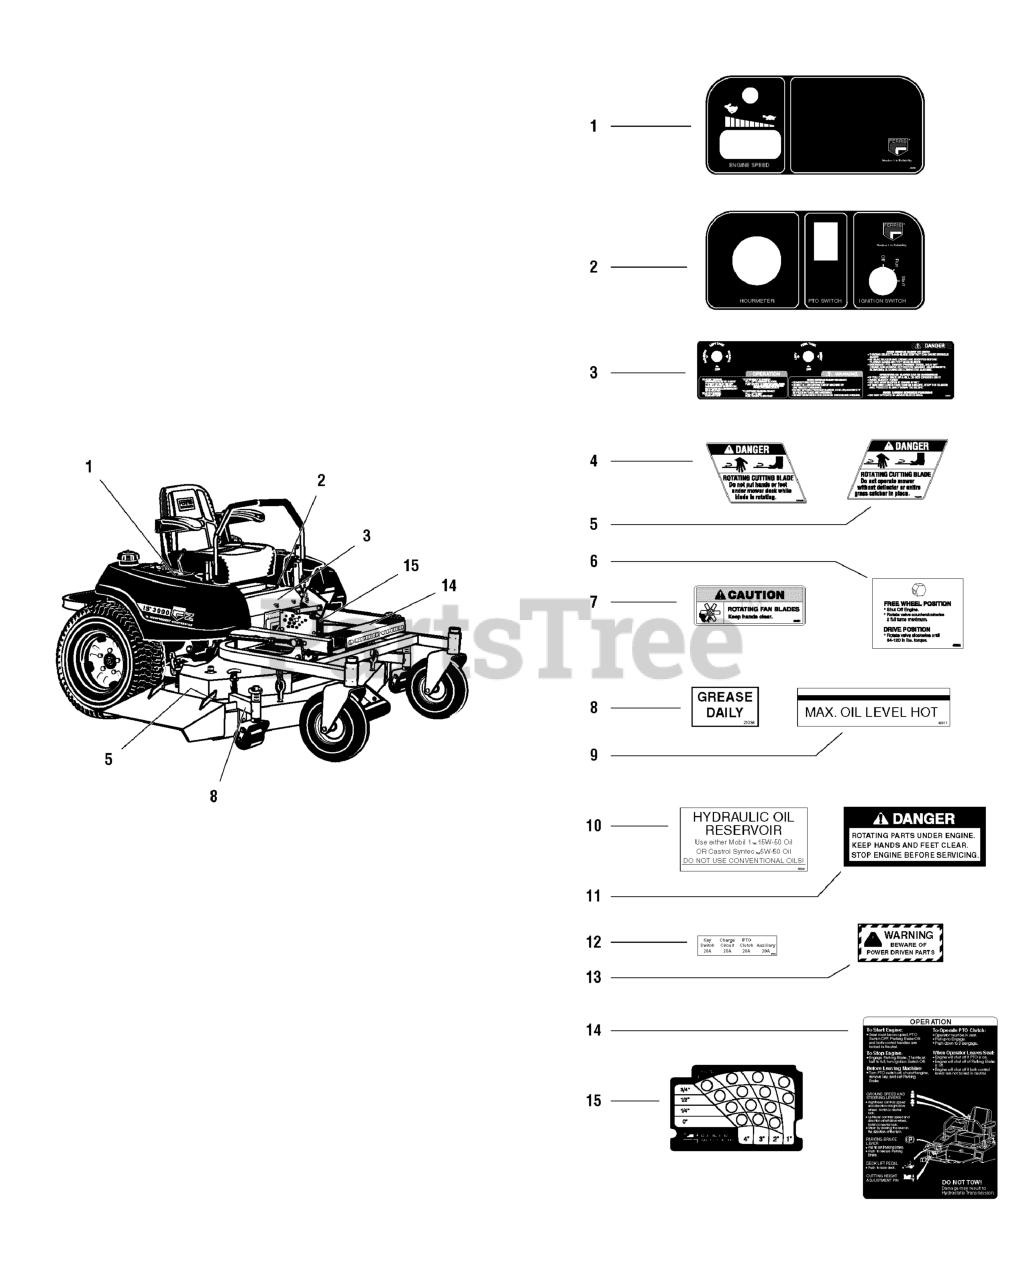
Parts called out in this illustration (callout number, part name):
1	DECAL, Control Panel-RH
2	DECAL, Control Panel-LH
3	DECAL, Safety/Instruction
4	DECAL, Danger (Hand Under Deck)
5	DECAL, Danger (Chute In Place)
6	DECAL, Hydro Release Valve
7	DECAL, Caution Fan
8	DECAL, Grease Daily
9	DECAL, Max. Oil Level
10	DECAL, Oil Reservoir
11	DECAL, Danger, Rotating
12	DECAL, Fuse Location
13	DECAL, Warning
14	DECAL, Operation
15	DECAL, Deck Height
